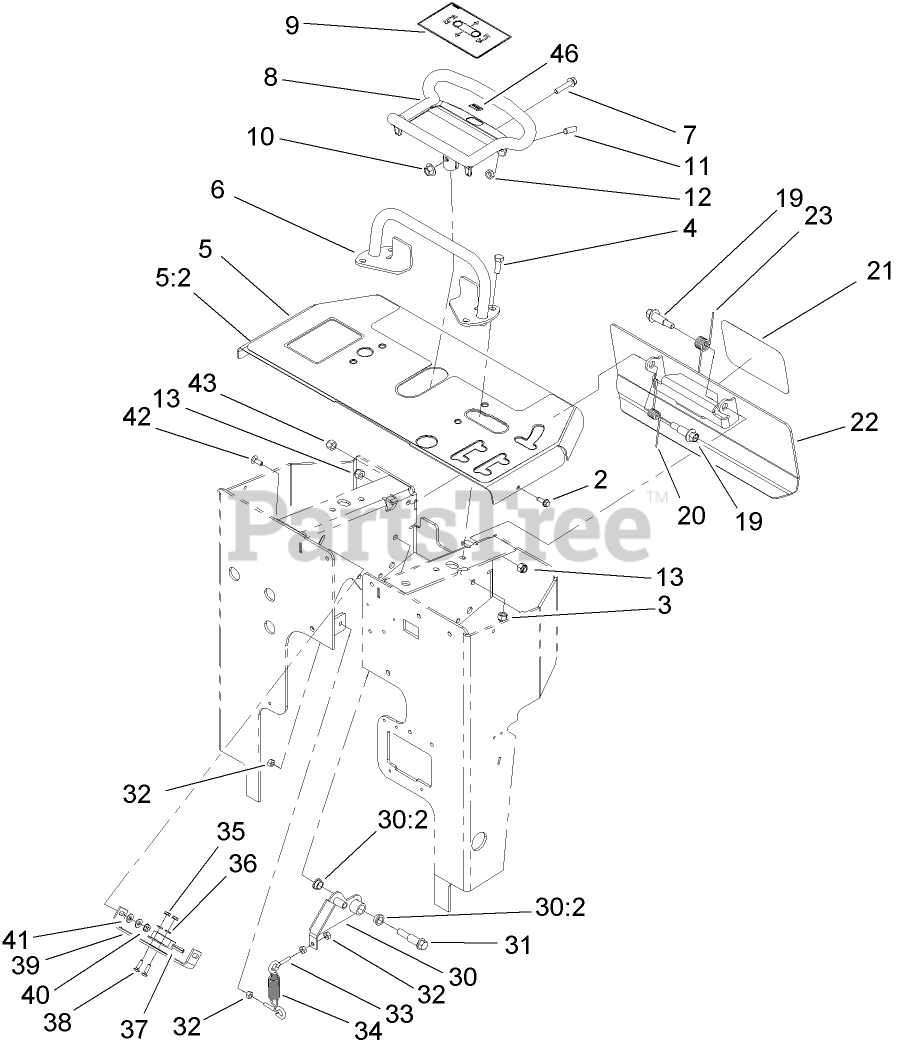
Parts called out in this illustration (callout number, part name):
2	SCREW-HWH, THREAD ROLL
3	NUT-LOCK, NI
4	SCREW-HH
5	CONTROL PANEL ASM
5:2	DECAL-CONTROL PANEL
6	REFERENCE BAR ASM
7	SCREW-HHF
8	HANDLE-CONTROL
9	DECAL-TRACTION
10	NUT-FLANGE
11	SCREW-SET, HSH
12	NUT-JAM
13	NUT-LOCK, NI
19	BOLT-SHOULDER
20	SPRING-TORSION, RH
22	REVERSE PLATE ASM
23	SPRING-TORSION, LH
30	NEUTRAL CENTERING LEVER ASM
30:2	BUSHING-FLANGE
31	BOLT-SHOULDER
32	NUT-HEX
33	BOLT-EYE
34	SPRING-EXTENSION
35	NUT-KEPS
36	WASHER-FLAT
37	SWITCH-PROXIMITY
38	SCREW-CARR
39	PLATE-SWITCH
40	NUT-KEPS
41	WASHER-FLAT
42	BOLT-CARR
43	NUT-LOCK
46	DECAL
